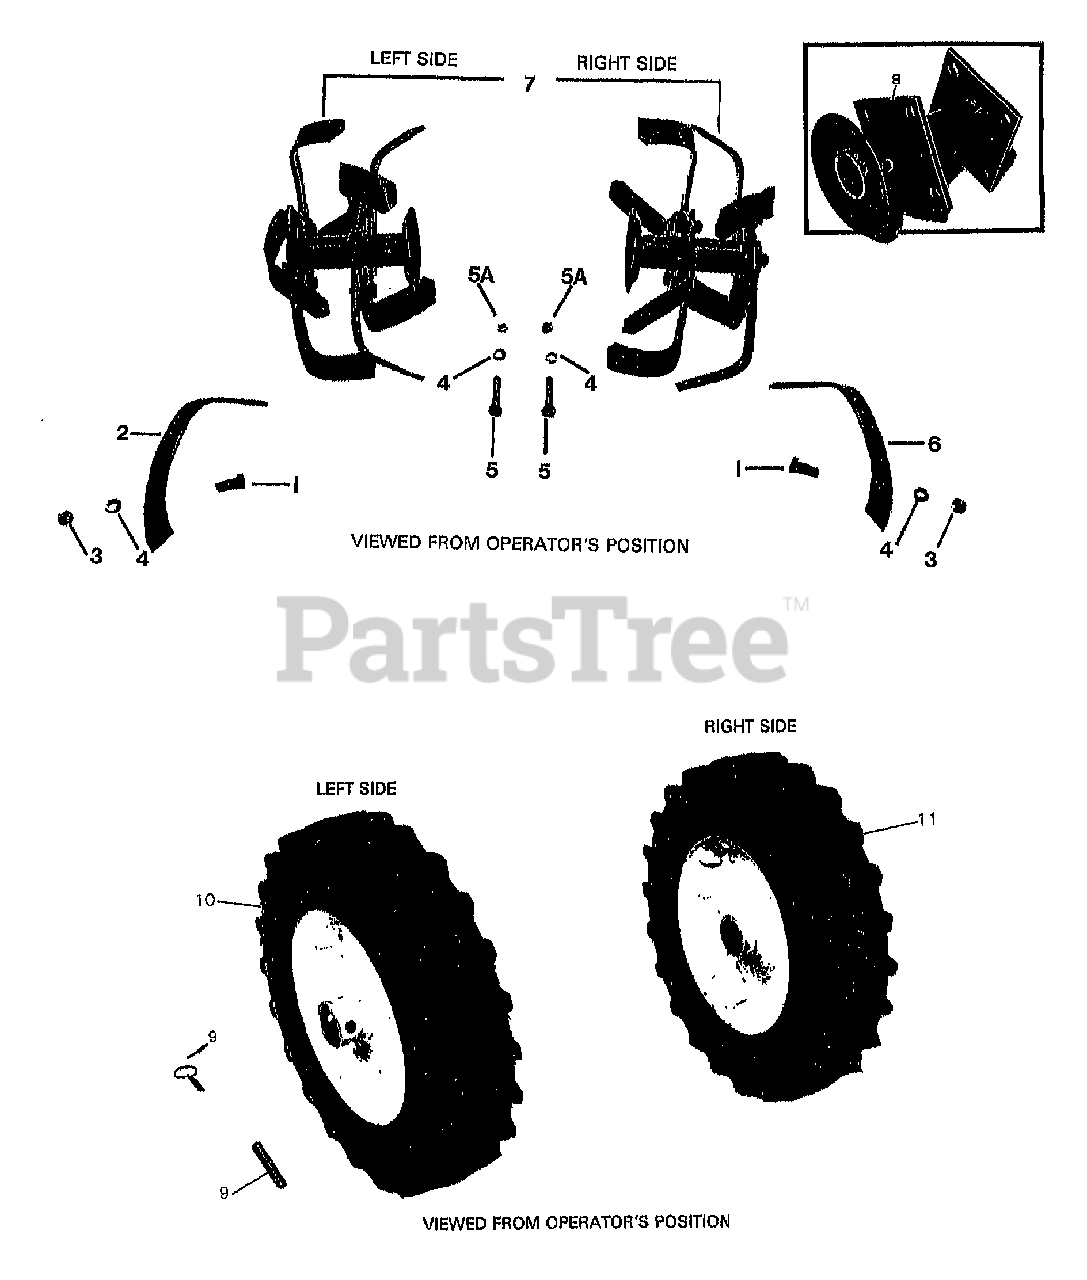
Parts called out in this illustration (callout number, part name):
1	SCR-HH 3/8-16X1.0 G5 ZP
2	TINE-BOLO RT W/HDW
3	NUT-HEX 3/8-16 ZP
4	WASHER-LK .375 @ DEPL
5	SCR-HH 3/8-16X2.00 G8 (HOLDER TO TILLER SHAFT)
5A	NUT-H/LK 3/8-16
6	TINE-BOLO LT W/HDW
7	PONY TINES W/HLDRS
7	P-1 BOLO&HOLDS
8	WELD-TINE HOLDER
8	T HOLDER
9	PIN-SPIRAL .313 X 1.5
9	PIN-QUICK RELEASE
10	ASSM-WHEEL/TIRE LT
11	ASSM-WHEEL/TIRE RT
11	ASSM-TIRE LT 4.10 X 6"
11	ASSM-TIRE RT 4.10 X 6"
11	WHEEL/TIRE-LT PONY 2
11	WHEEL/TIRE-RT PONY 2
